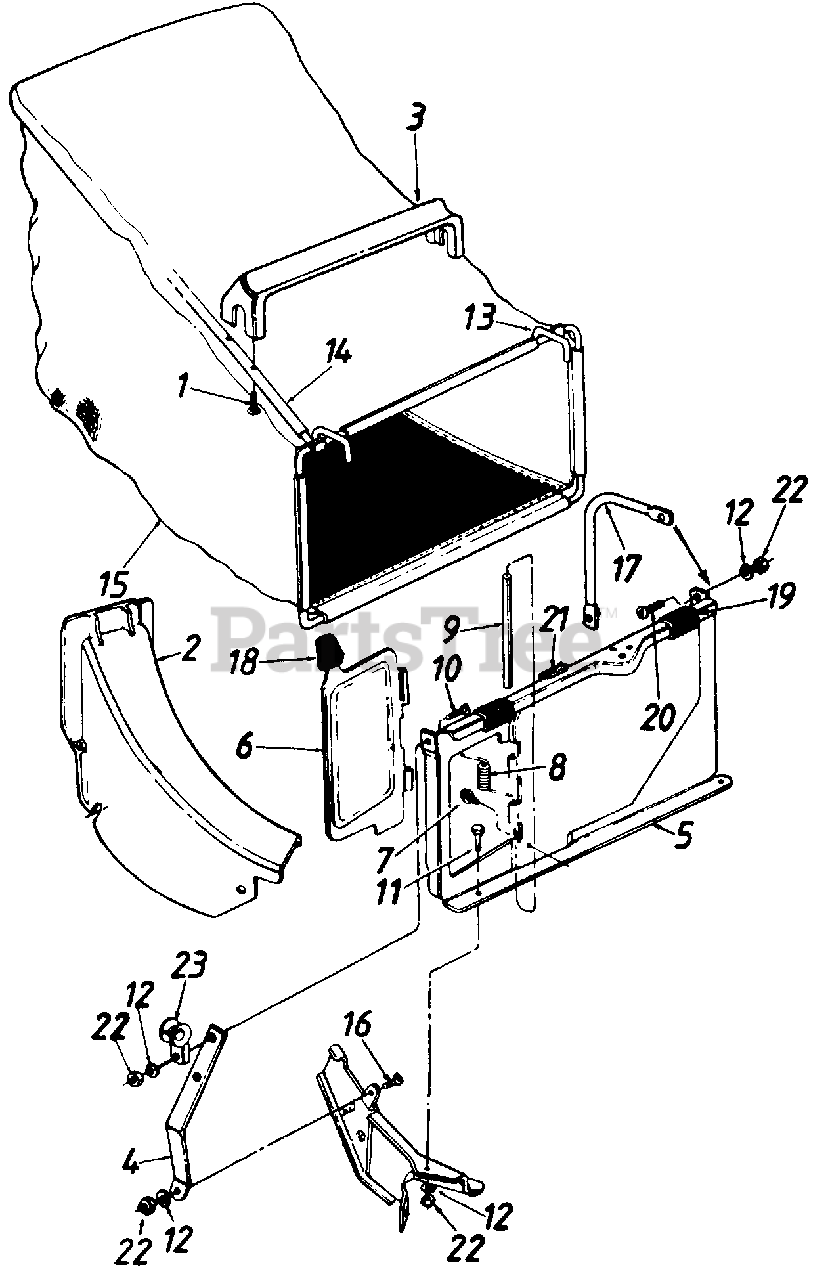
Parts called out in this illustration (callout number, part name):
1	Hex AB-Tap Scr. #12 x 1.25" Lg.
2	Rear Discharge Chute Ass'y.
3	Bag Handle
4	Panel Support Brkt.
7	Hex B-Tap Scr. #10 x .38"
8	Torsion Spring
9	Pivot Pin
10	Truss Mach. Scr. 1/4-20 x 3/4" Lg.
11	Hex Bolt 1/4-20 x .50" Lg.
12	L-Wash. 1/4" l.D.
13	Front Grass Catcher Frame
14	Rear Grass Catcher Frame
15	21" Rear Discharge Grass Bag
16	Hex Bolt 1/4-20 x .62" Lg.
17	Catcher Panel Support Arm
18	Door Grip
19	Panel Clip
20	Truss Mach. Scr. 1/4 20 x .62" Lg.
21	Foam Strip
22	Hex Nut 1/4-20 Thd.
23	Rope Guide
